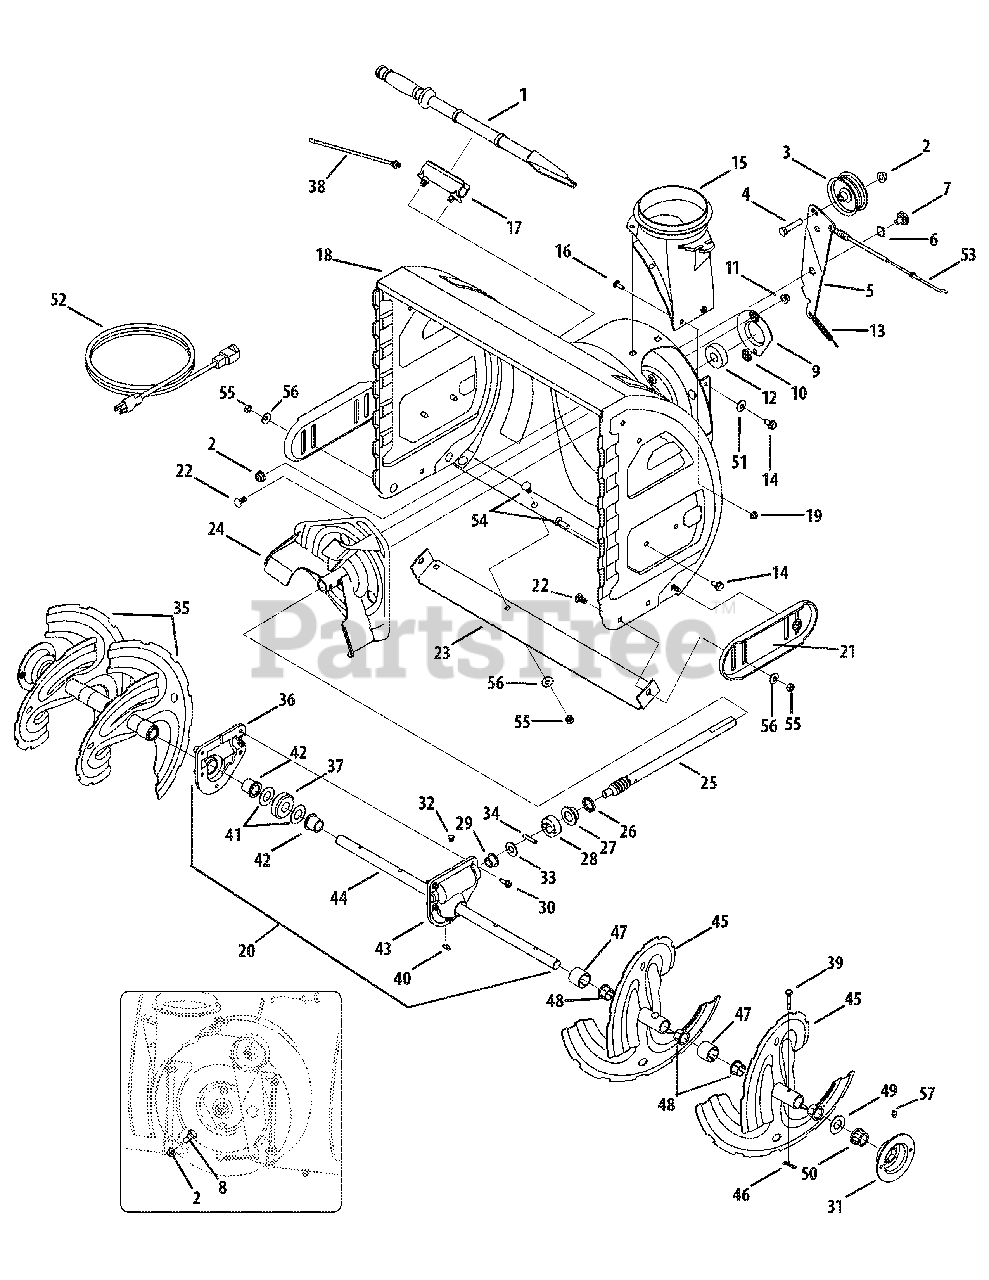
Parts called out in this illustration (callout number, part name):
1	Clean-Out Tool
2	Flange Lock Nut
3	Flat Idler Pulley
4	Hex Bolt, 3/8-16 x 1.75
6	Wave Washer
7	Shoulder Screw
8	Shoulder Screw
9	Bearing Housing
11	Flange Lock Nut, 5/16-18
12	Ball Bearing
13	Extension Spring
15	Chute Adapter
16	Carriage Screw, 1/4-20 x 0.75
17	Clean-out Tool Mtg. Bracket
18	Housing Assembly, Auger, 22"
19	Flange Lock Nut, 1/4-20
20	Gearbox Assembly, Auger, 22"
20	Gearbox Assembly, Auger, 24"
20	Gearbox Assembly, Auger, 26"
20	Gearbox Assembly, Auger, 28"
20	Gearbox Assembly, Auger, 30"
21	Skid Shoe, Standard
21	Skid Shoe, POLYMER
21	Deluxe Polymer Reversible Shoe Kit
21	Skid Shoe, Stainless
22	Bolt, Carriage, 5/16-18 x .75
22	Bolt, Carriage, 5/16-18 x 1.00
23	Stainless Steel Shave Plate, 26"
23	Stainless Steel, Shave Plate, 28
23	Stainless Steel Shave Plate, 30"
25	Worm Shaft
27	Flange Bearing
28	Thrust Collar
29	Flange Bearing
30	TT Screw, 1/4-20 x 0.75
33	Flat Washer
36	Reducer Hsg.-RH (Incl Ref. 44-45)
37	Worm Gear, 20T
38	Cable Tie
40	Hi-Pro Key
41	Flat Washer
42	Flange Bearing
43	Reducer Hsg.- LH
44	Axle, Auger, 22"
44	Axle, Auger, 24"
44	Axle, Auger, 26"
44	Axle, Auger, 28"
44	Axle, Auger, 30"
46	Bow Tie Cotter Pin
48	Flange Bushing
49	Flat Washer
50	Hex Flange Bearing
51	Bell Washer
52	Extension Cord. 3-Prong
53	Auger Clutch Cable
54	Carriage Bolt, 5/16-18 x .75 (SS)
54	Carriage Bolt, 5/16-18 x .75
55	Hex Nut, 5/16-18 (SS)
55	Flange Lock Nut, 5/16-18
56	Bell Washer, .340 x .872 x .060
57	Drive Lube Fitting
